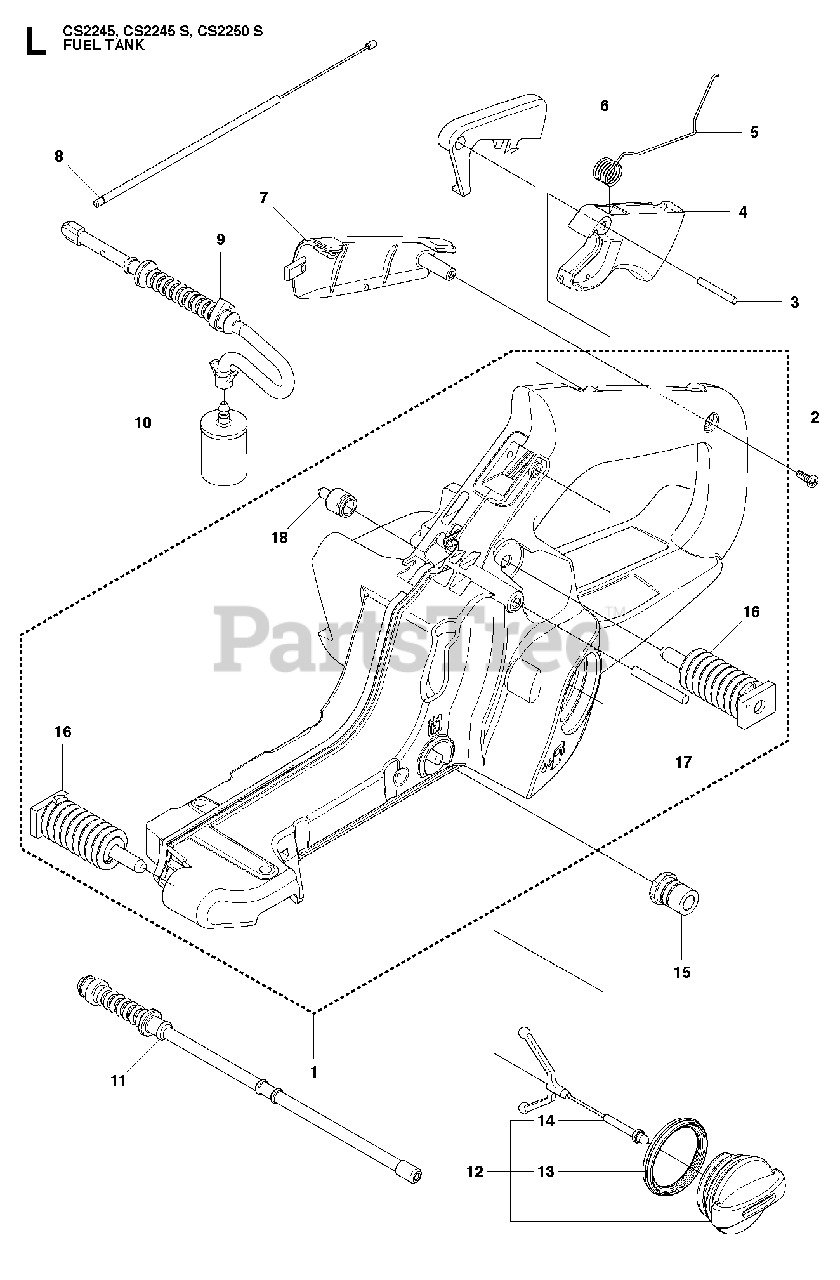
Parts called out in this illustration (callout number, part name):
1	RP FUEL TANK ASSY
4	THROTTLE TRIGGER
6	THROTTLE LOCKOUT
7	HANDLE INSERT
8	THROTTLE CABLE ASSY
9	RP FUEL HOSE
10	FUEL FILTER
11	RP RETURN HOSE
12	TANK CAP ASSY
13	SEALING
14	HOLDER
15	LATERAL SUPPORT
16	ANTI VIBRATIONS ELEMENT
17	GROOVED PIN
18	FUEL TANK VENT
